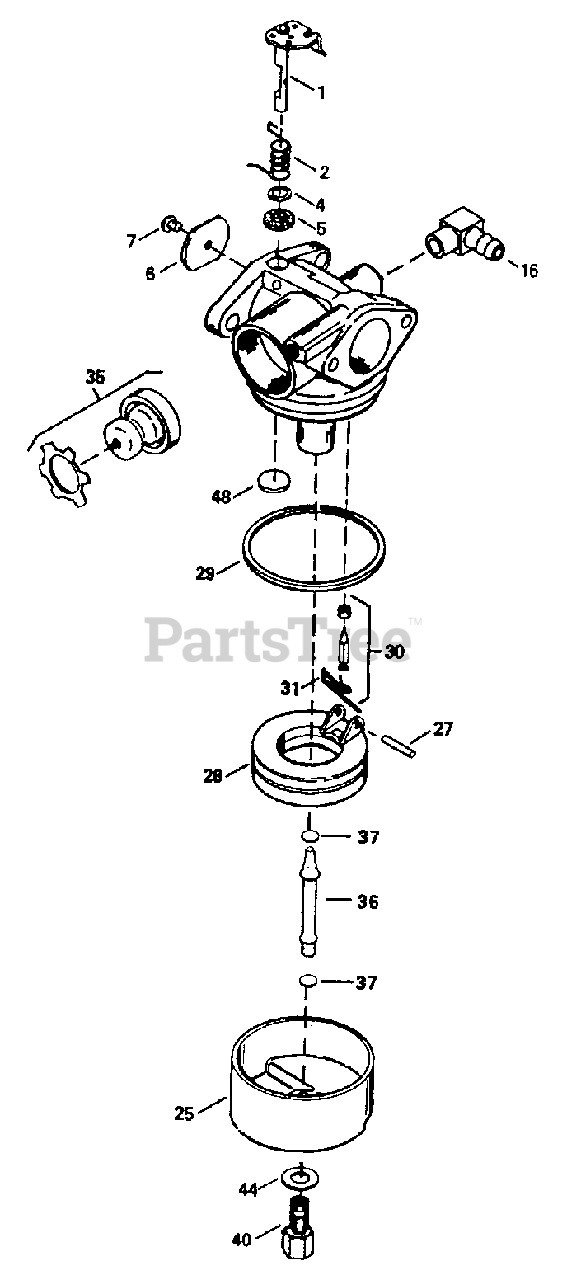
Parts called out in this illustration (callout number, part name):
1	Throttle Shaft & Lever Assembly
2	Throttle Return Spring
4	Dust Seal Washer
5	Dust Seal (Throttle)
6	Throttle Shutter
7	Shutter Screw
16	Fuel Fitting
25	Float Bowl
27	Float Shaft
29	Float Bowl "O" Ring
30	Inlet Needle, Seat, & Clip (Incl. 31)
31	Spring Clip
35	Primer Bulb/Retainer Ring
36	Main Nozzle Tube
37	O-Ring, Main Nozzle Tube
40	High Speed Bowl Nut
44	Bowl Nut Washer
48	Welch Plug, Atmospheric Vent
